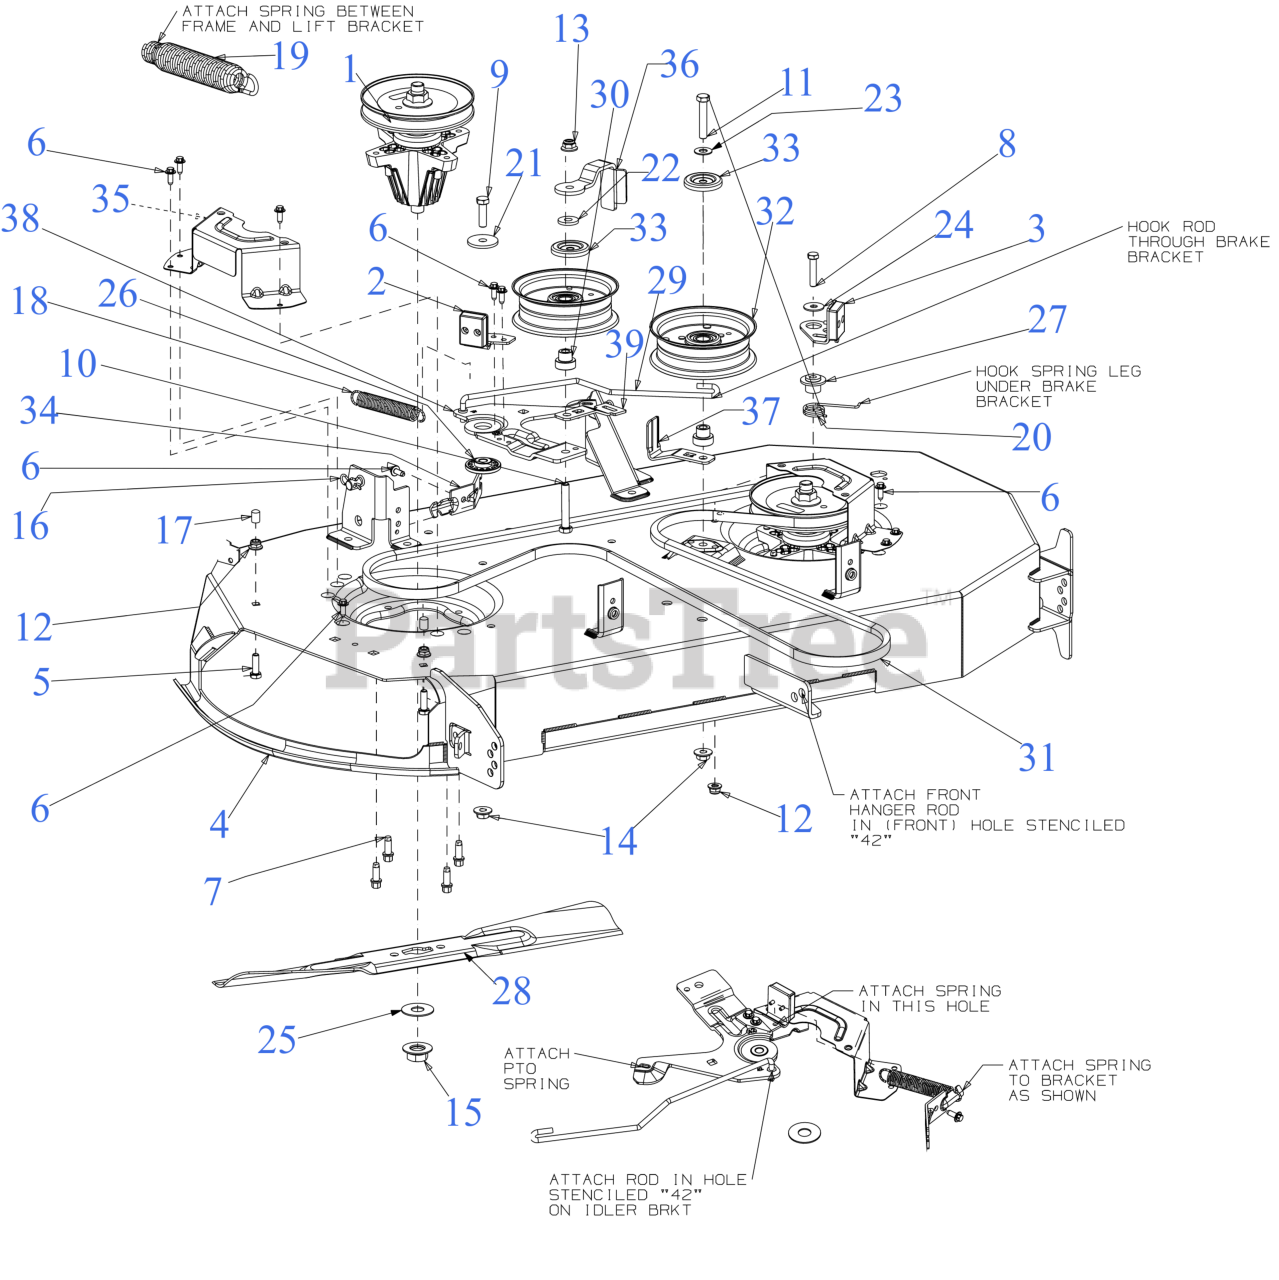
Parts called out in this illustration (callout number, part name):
1	SPINDLE ASSEMBLY (6.3 DIA)
2	DECK BRAKE ASSEMBLY (RH)
3	DECK BRAKE ASSEMBLY
4	42" FAB DECK SHELL
5	SCREW 5/16-18 x 1.0 GR5
6	SCREW M6-1 x .625
7	SCREW 5/16-18 x .875
8	SCREW 5/16-18 x 1.5 LG
9	SCREW 3/8-16 x 1.25 GR5
10	SCREW 3/8-16 x 2.25 GR5
11	SCREW 3/8-16 x 2.0 GR 8
12	FLANGE LOCK NUT 5/16-18
13	NUT
14	FLANGE LOCK NUT
15	HEX FLANGE NUT 5/8-18 GR5
16	BOW TIE COTTER PIN
18	EXTENSION SPRING
19	LIFT ASSIST SPRING (SMALL)
20	TORSION SPRING
21	FLAT WASHER .390x1.500x.134
22	FLAT WASHER .385 x 1.00 x .135
23	FLAT WASHER .401X.88
24	FLAT WASHER 344X1.00
25	FLAT WASHER .635X1.585X.062 HDN
26	SHOULDER SPACER
27	DOUBLE SHOULDER SPACER .750 x .135
28	21.23" BLADE (2IN1) (S SHAPE CENTER HOLE)
28	Cub Cadet 42" HI LIFT BLADE SET (S SHAPE CENTER HOLE) (-05177A)
28	21.23" XTREME BLADE (2IN1) (S SHAPE CENTER HOLE)
28	Cub Cadet 42" XTREME BLADE SET (S SHAPE CENTER HOLE) (-05177-X)
28	21.23" LOW LIFT BLADE (S SHAPE CENTER HOLE)
28	Cub Cadet 42" LOW LIFT BLADE SET (S SHAPE CENTER HOLE) (-05177-L)
29	DECK BRAKE ROD
30	SHOULDER SPACER
31	V-BELT A SEC x 99.75
31	Cub Cadet 42" DECK DRIVE BELT
32	IDLER PULLEY 4.50" DIA
33	IDLER PULLEY CAP
34	ENGAGEMENT CABLE BRACKET
35	DECK BELT COVER
36	BELT KEEPER
38	42" IDLER BRACKET PIVOT
